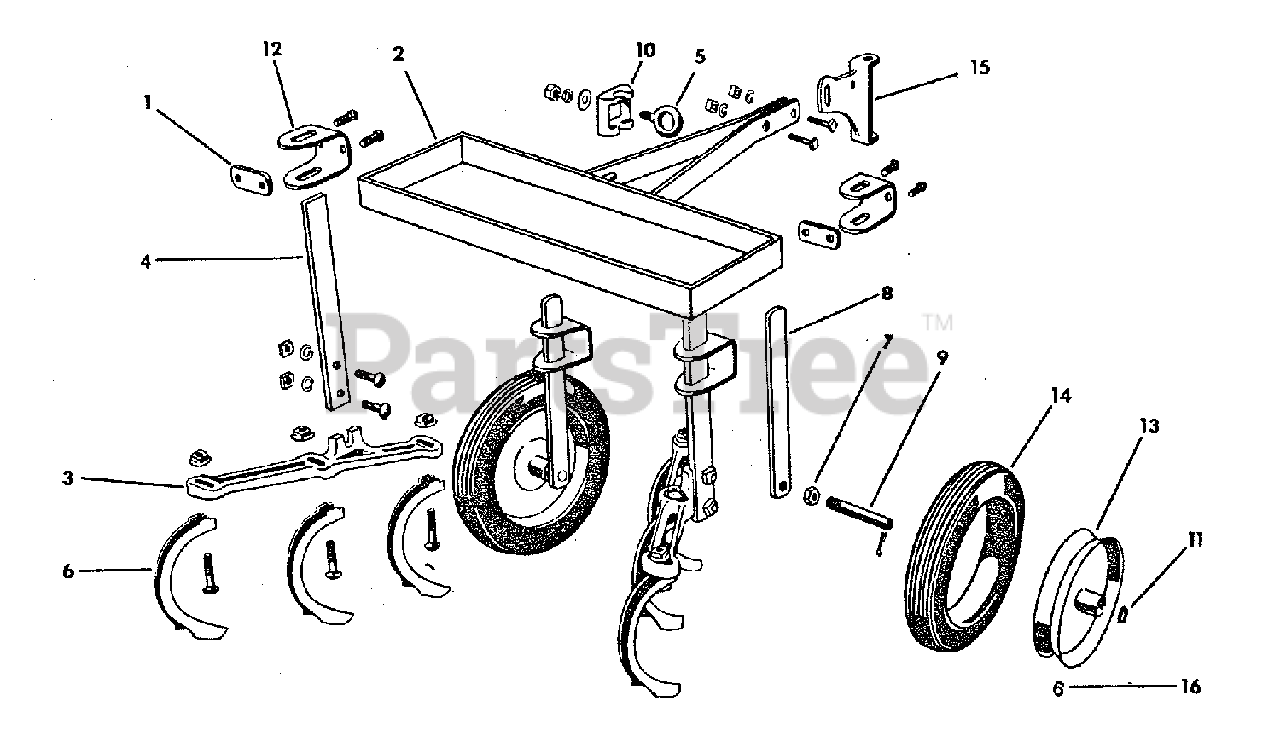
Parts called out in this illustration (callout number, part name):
1	NUT, Special
2	FRAME, Cultivator
3	HOLDER, Tool
4	STANDARD, Tool
5	BOLT, Eye
6	TOOTH, Cultivator
8	WHEEL STANDARD, Guage
9	WHEEL SPINDLE, Guage
10	TOOL CONTROL HANDLE BLOCK
11	WHEEL, Washer for Guage
12	CLAMP, Shank
13	WHEEL, Cultivator
15	END, Draw Bar
